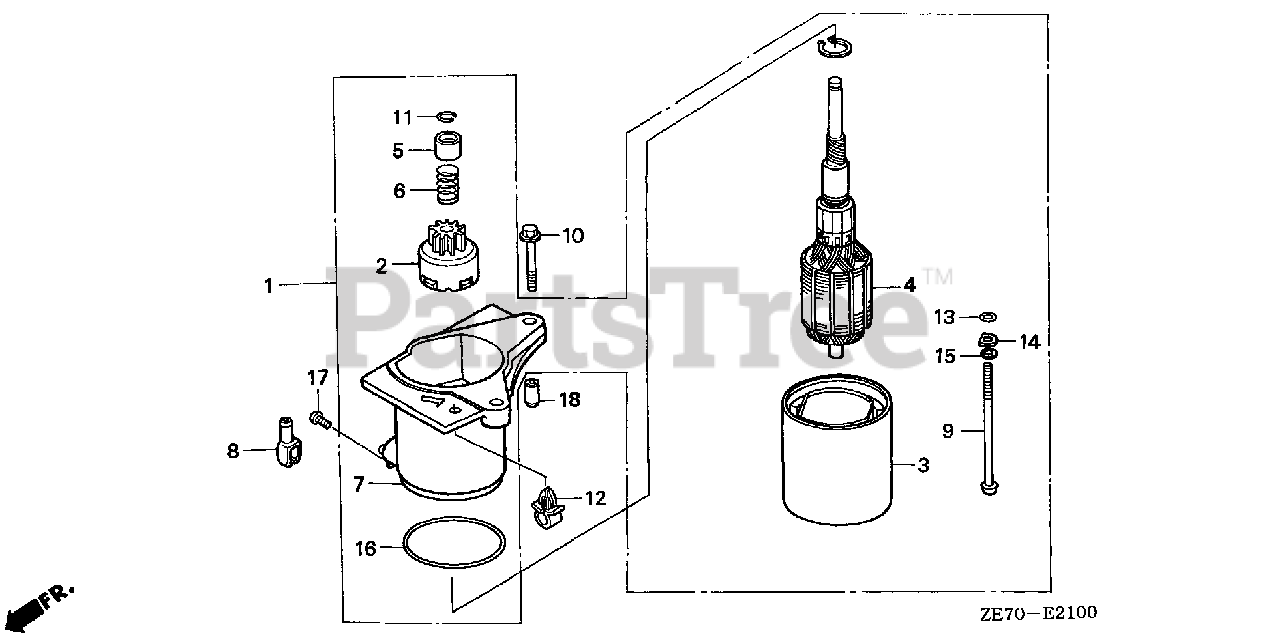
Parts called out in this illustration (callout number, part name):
1	MOTOR UNIT, STARTER
2	GEAR ASSY., PINION
3	YOKE ASSY.
4	ROTOR ASSY.
5	PIECE, STOPPER
6	SPRING, RETURN
7	BRACKET, FR.
8	COVER, TERMINAL
9	BOLT, SETTING
10	BOLT, FLANGE (6X32)
11	CIRCLIP (OUTER) (8.3MM)
13	O-RING
14	WASHER, SPECIAL
15	WASHER, SPRING
16	O-RING
18	PIN A, DOWEL (8X14)
